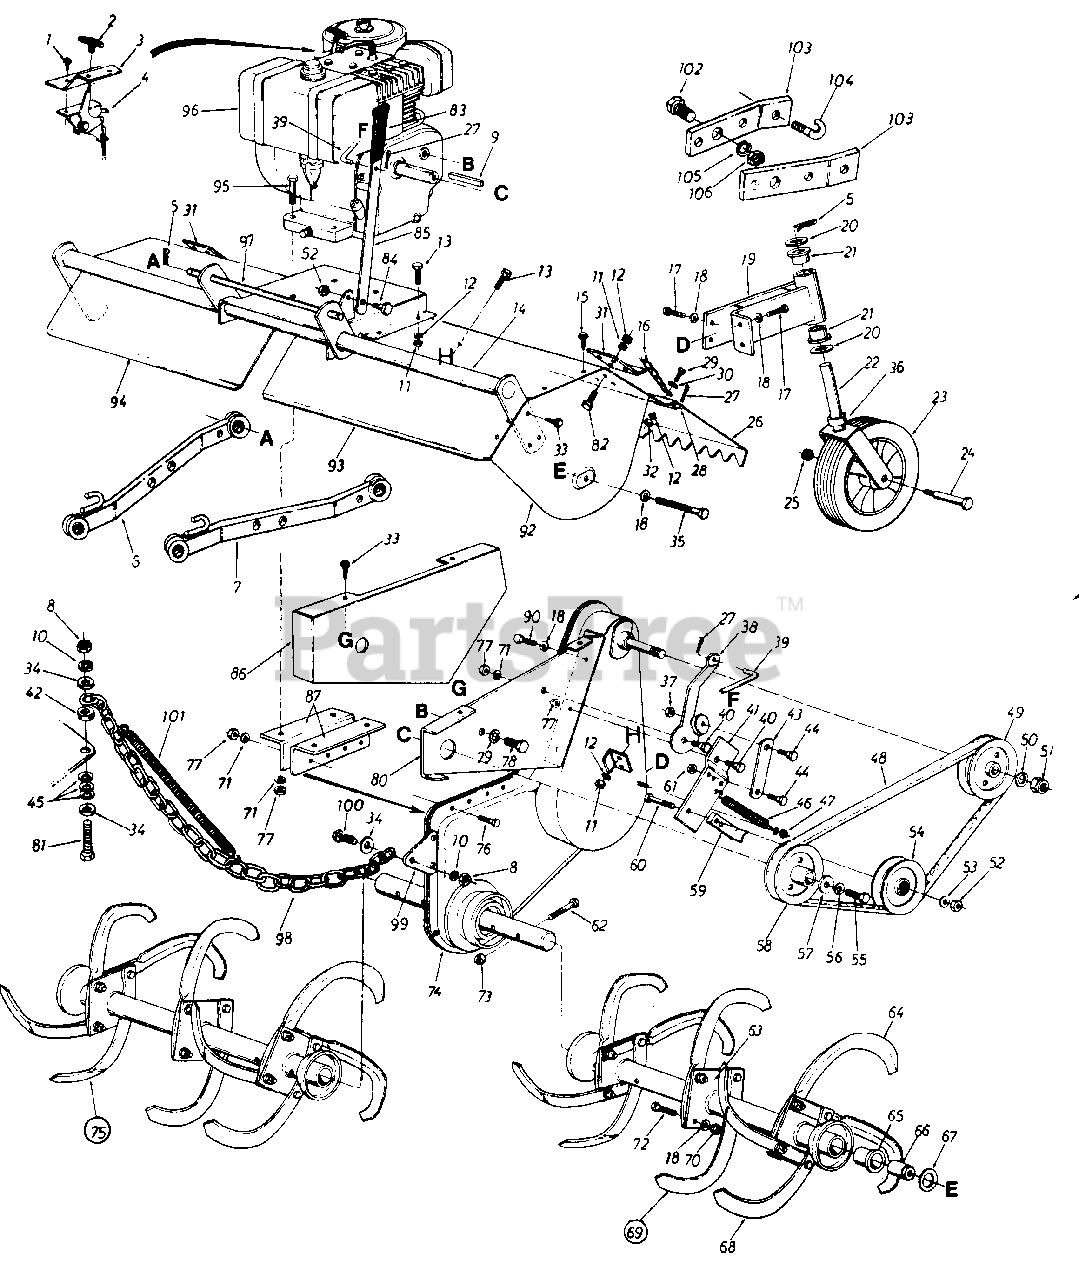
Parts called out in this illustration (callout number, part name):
1	Hex Wash. Hd. Self-Tap Scr. #8 x .50" Lg.
2	Throttle Control Knob-
3	Throttle Control Bracket
4	Throttle Control Ass'y. Comp.
5	Internal Cotter Pin
6	Draft Bar Ass'y.-R.H.
7	Draft Bar Ass'y.-L.H.
8	Hex Nut 3/8-24 Thd.
9	Sq. Key 1/4" x 1/4" x 2.00" Lg.
10	L-Wash. 3/8" I.D.
11	Hex Nut 1/4-28 Thd.
12	L-Wash. 1/4" I.D.
13	Hex Bolt 1/4-28 x .62" Lg.
16	#2 Dog Chain x 20" Lg.
17	Hex Wash. Hd. Self-Tap Scr. 3/8-24 x .75" Lg.
18	L-Wash. 3/8" I.D.
21	Flange Bearing 3/4" I.D. x 1.00" O.D.
24	Shoulder Bolt .623" I.D. x 3.62" Lg.
25	Hex Cent. L-Nut 7/16-14 Thd.
28	L.H Flap Rod
29	Hex Bolt 1/4-20 x .62" Lg.
30	Fl-Wash. 1/4" I.D.
33	Hex Wash. Hd. Self-Tap Scr. 1/4" x .62" Lg.
34	Fl-Wash. .385" I.D. x 1.0" O.D. x .135 Thk.
35	Hex Bolt 3/8-16 x 1.25" Lg.
36	Spacer .752" I.D. x 1.25" O.D.
37	Hex Cent. L-Nut 5/16-18 Thd.
40	Shoulder Bolt 7/16" Dia. x 1.75" Lg.
45	Fl-Wash. .406" I.D. x .74 O.D. x .063 Thk.
46	Extension Spring .62" O.D. x6.12" Lg.
47	Hex Crown Nut 3/8-24 Thd.
48	"V"-Belt 1/2" x 43" Lg. (Kevlar)
49	1/2" "V"-Pulley 4.75" O.D. x .625" Bore
50	L-Wash. 5/8n I.D.
51	Hex Ins. L-Nut 5/8-18 Thd.
52	Hex Cent. L-Nut 3/8-16 Thd.
53	Fl-Wash. 3/8n I.D.
54	Idler Pulley 4.0" O.D.
55	Hex Bolt
56	L-Wash. 7/16" I.D.
57	Fl-Wash. 7/16" I.D. x 1.38" O.D.
58	1/2" "V"-Pulley .475" O.D. x 1.00" Bore
61	Hex Cent. L-Nut 5/16-18 Thd.
62	Hex Bolt 7/16-14 x 2.00" Lg.
66	Spacer
67	Thrust Wash. 1/2" I.D. x 1.55" O.D.
71	L-Wash. 5/16" I.D.
72	Hex Bolt 3/8-24 x 1.5" Lg.
73	Hex Cent. L-Nut 7/16-14 Thd.
77	Hex Nut 5/16-18 Thd.
78	Hex Bolt 1/2-20 x .88" Lg. (Grade 5)
79	L-Wash. 1/2" I.D.
80	Clutch Support Bracket
81	Hex Bolt 3/8-24 x 1.75 Lg.
82	Hex Bolt 1/4-28 x .75" Lg.
83	Plastic Grip
84	Shoulder Bolt .498 Dia. x .212 Lg.
85	Clutch Handle
96	8 H.P. Engine
97	Tiller Mounting Shaft 16" Lg.
98	Chain 23 Lg.
99	Tiller Mounting Bracket
100	Hex Bolt 3/8-24 x 1.25" Lg.
101	Extension Spring
102	Hex Bolt 5/8-18 x 1.62" Special
103	Drag Link Extension
104	Hitch Chain Hook
105	L-Wash. 5/8" I.D.
106	Hex Jam Nut 5/8-18 Thd.
